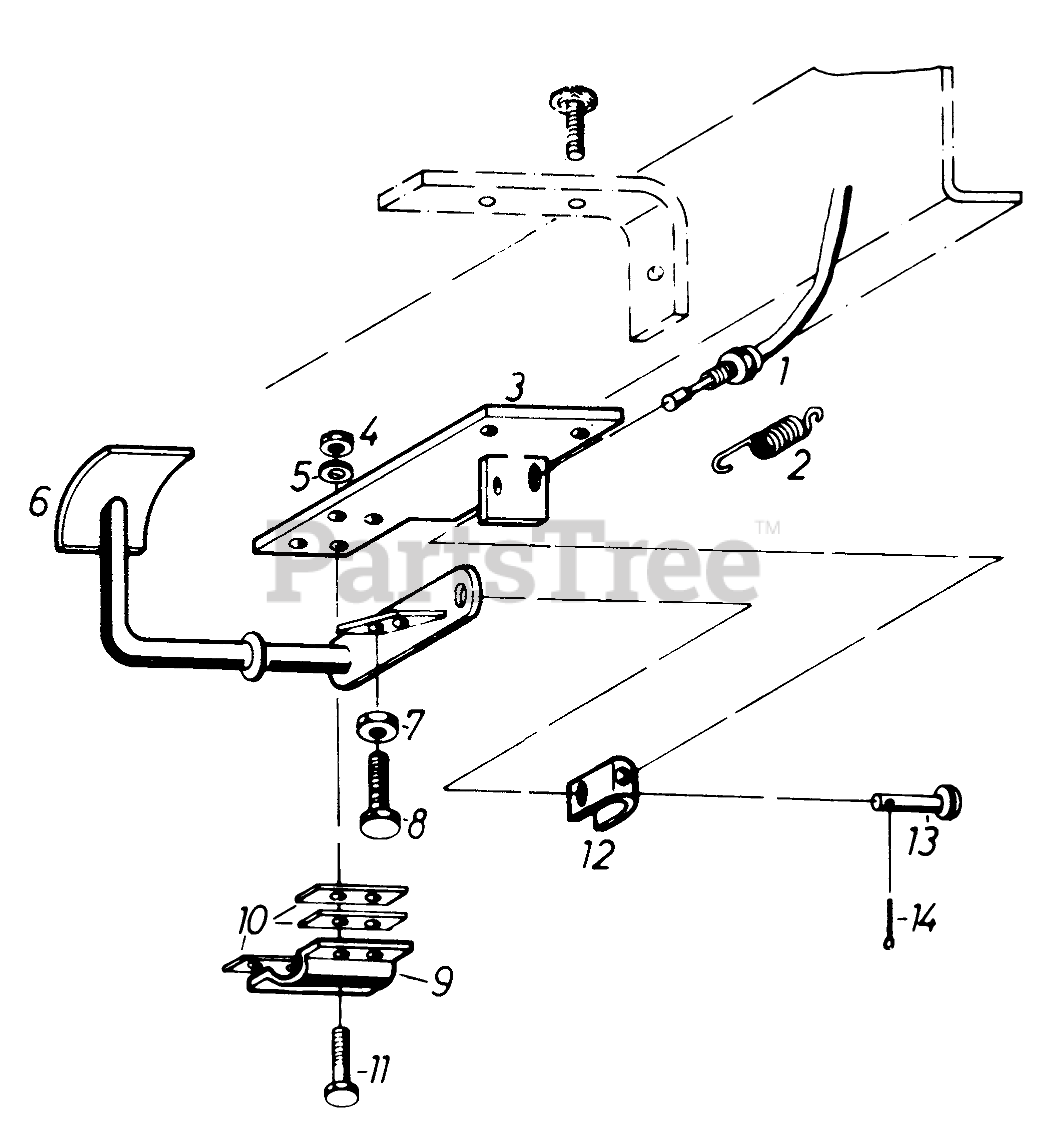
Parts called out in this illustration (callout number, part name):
1	BOWDEN WIRE
2	Spring
3	Support Assy.
5	Washer
6	Gas Pedal Assy.
9	Gas Pedal Bracket
11	Screw
